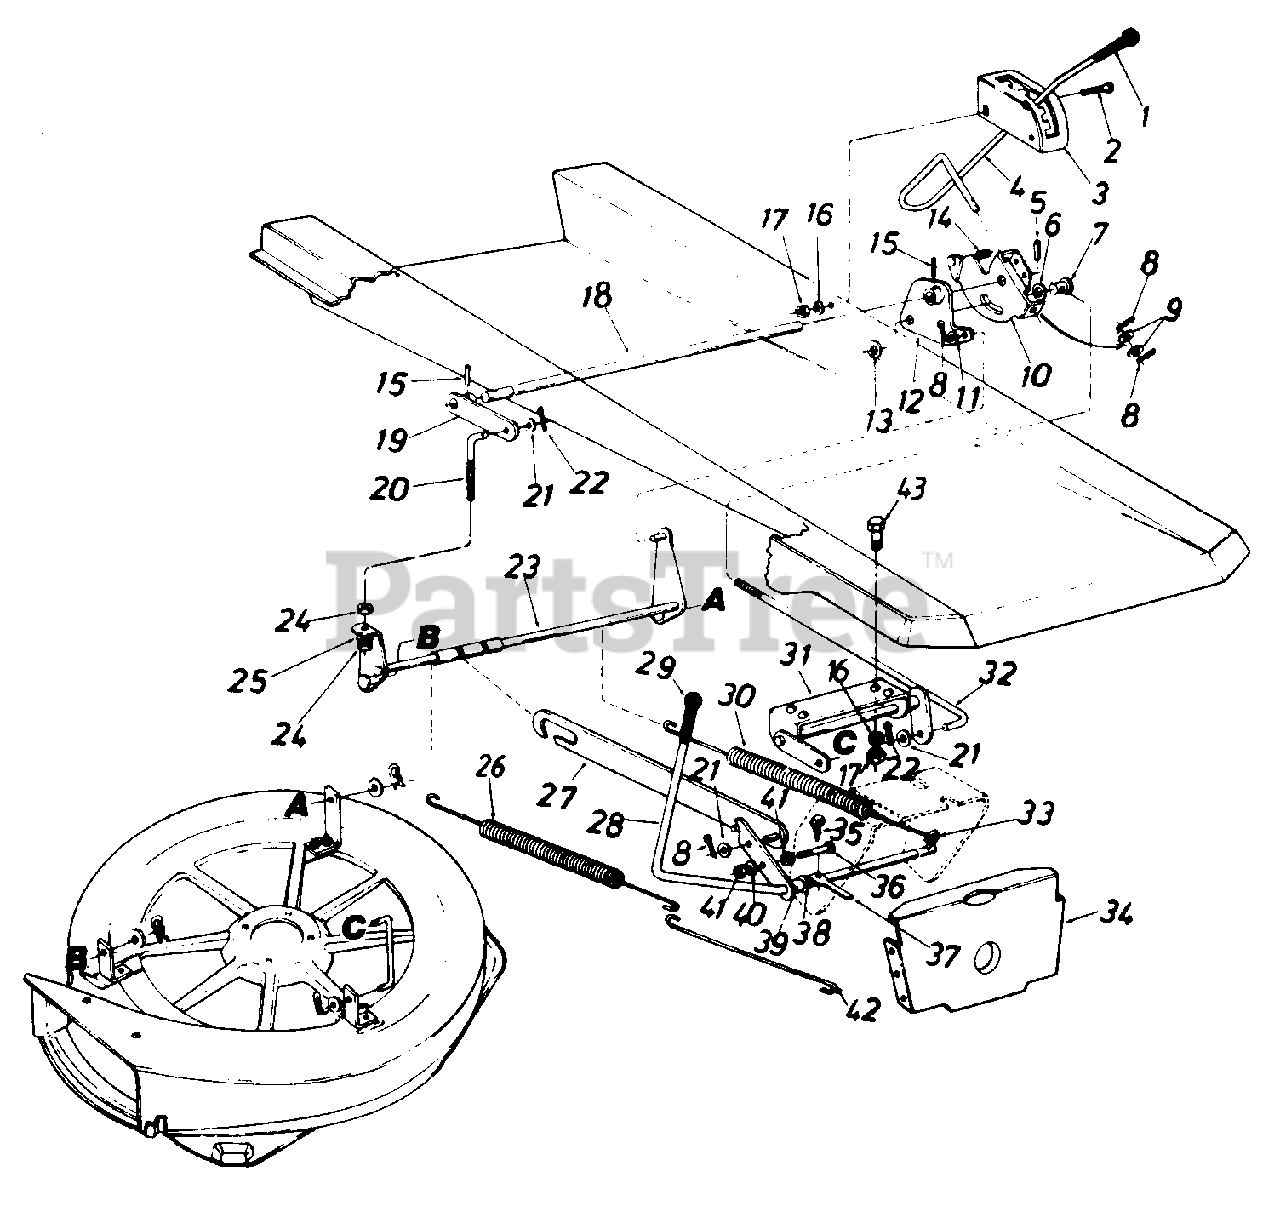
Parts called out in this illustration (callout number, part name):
2	Truss Mach. Scr. 5/16-18 x .75" Lg.
5	Spring Pin Spir. 3/16" Dia. x 1.50" Lg
6	Fl-Wash. 385" I.D. x 37" O.D.
7	Adj. Ferrule Deck Lift Handle
8	Cotter Pin 1/8" Dia. x 1.00" Lg.
9	Fl-Wash. .531" I.D. x 930" O.D.
10	Deck Lift Handle Retainer Ass'y.
11	Fl-Wash. .385" I.D. x 37" O.D.
12	Deck Lift Brkt. Ass'y.-L.H.
13	Fl-Wash. 535" I.D. x 1.04" O.D.
14	Compression Spring .50" Dia. x 1.0" Lg.
15	Spring Pin Spir. 1/4" Dia. x 1.50" Lg
16	L-Wash. 5/16" I.D.
17	Hex Nut 5/16-18 Thd.
18	Rear Hgt. Adj. Shaft
19	Deck Lift Brkt. Ass'y.-R.H.
20	Deck Adj. Scr. 3/8-16 Thd.
21	Fl-Wash. 885" I.D. x .87" O.D.
22	Intern. Cotter Pin 1/2" Dia.
23	Deck Link Ass'y.-Rear
24	Hex Nut 3/8-16 Thd.
25	L-Wash. 3/8" I.D.
26	Extension Spring .73" O.D. x 1 3.84" Lg.
30	Extension Spring .73" O.D. x 13.84" Lg.
31	Deck Lift Ass'y.-Front
32	Deck Lift Connecting Rod
33	Clevis Pin Special .250" Dia.
34	Pivot Bar Bracket
35	Hex TT-Tap Scr. 1/4-20 x .75" Lg.
36	Hex Bolt 5/16-18 x 1.50" Lg. (Grade 5)
37	Switch Actuator
38	Fl-Wash. .531" I.D. x ,930" O.D.
39	Spacer .511" I.D. x .70" O.D. x .38" Lg.
40	L-Wash. 5/16" I.D.
41	Hex Nut 5/16-18 Thd.
42	Spring Hook
43	Hex Bolt 5/16-18 x .75" Lg.
